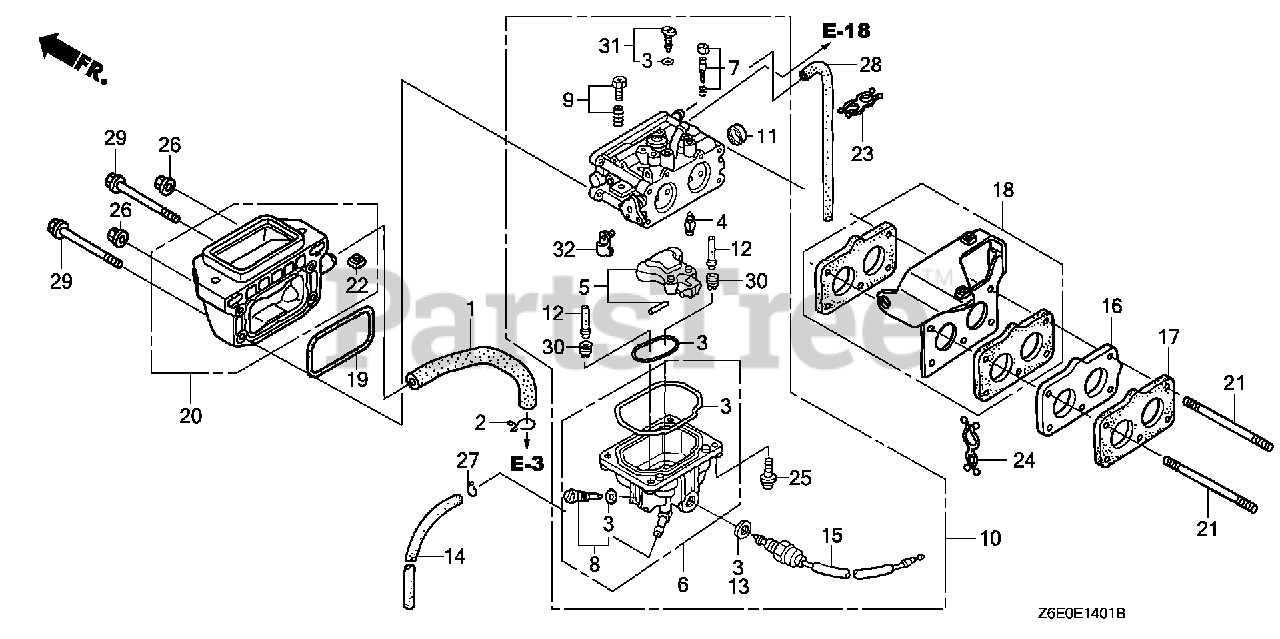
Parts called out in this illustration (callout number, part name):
1	TUBE, BREATHER
2	CLIP, BREATHER TUBE
3	GASKET SET
4	VALVE SET, FLOAT
6	CHAMBER SET, FLOAT
7	SCREW SET, PILOT
8	SCREW SET, DRAIN
9	SCREW SET, THROTTLE
10	CARBURETOR ASSY. (BK04A A)
11	CAP, CHOKE DUST
12	NOZZLE, MAIN
13	WASHER, PLAIN
14	TUBE, DRAIN
15	VALVE ASSY., SOLENOID (KEIHIN)
16	INSULATOR, CARBURETOR
17	GASKET, CARBURETOR
18	STAY, FUEL PUMP
19	GASKET, AIR CLEANER
20	ELBOW, AIR CLEANER
21	BOLT, STUD (6X113)
22	NUT, INSERT (6MM)
23	CLIP, WIRE HARNESS
24	CLIP, PURSE LOCK
25	SCREW, PAN (4X12)
26	NUT, FLANGE (6MM)
27	CLIP, TUBE (B8)
28	BULK HOSE, VACUUM (4.5X1000) (4.5X540)
29	BOLT, FLANGE (6X115)
30	JET, MAIN (#82)
30	JET, MAIN (#85)
30	JET, MAIN (#88)
31	JET SET, PILOT (#40)
32	ARM, THROTTLE LINKAGE
